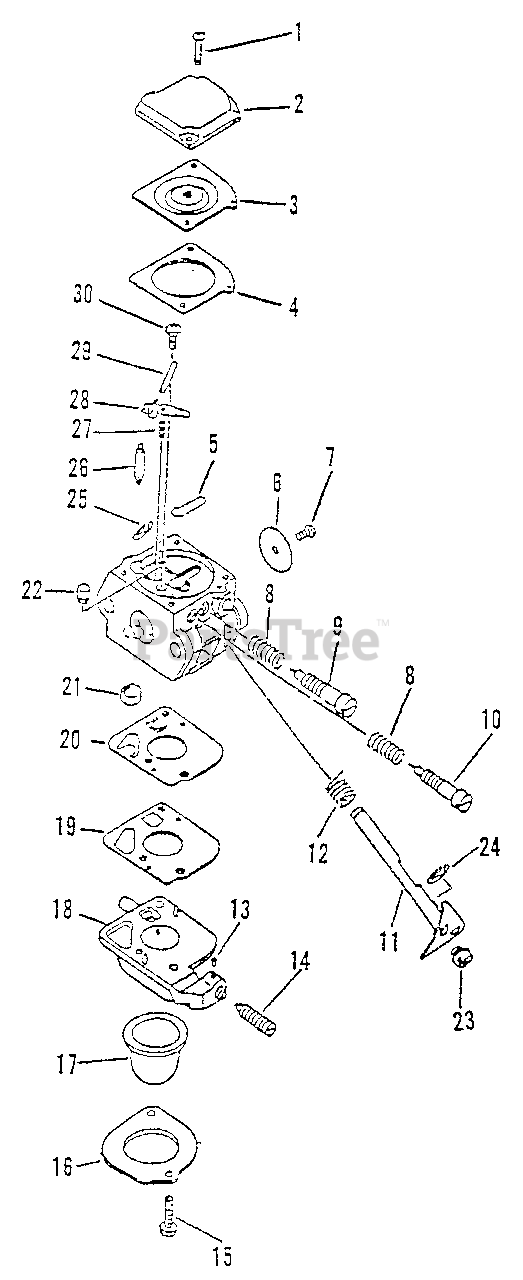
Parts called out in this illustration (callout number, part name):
2	COVER, METERING
3	DIAPHRAGM
4	GASKET, DIAPHRAGM
5	PLUG, WELCH
6	VALVE, THROTTLE
9	NEEDLE - LOW SPEED
10	NEEDLE - MIXTURE
11	SHAFT, THROTTLE
12	SPRING, RETURN
13	PIECE, FRICTION
14	SCREW, IDLE ADJUST
15	SCREW, RETAINER
16	RETAINER, PURGE BULB
17	BULB, PURGE
18	BASE, PURGE
19	GASKET, PUMP
20	DIAPHRAGM, PUMP
21	STRAINER
22	NOZZLE, CHECK VALVE
24	RING, RETAINING
25	RING, RETAINING
26	VALVE, NEEDLE
27	SPRING, METERING LEVER
28	LEVER, METERING
29	PIN, METERING LEVER
30	SCREW
